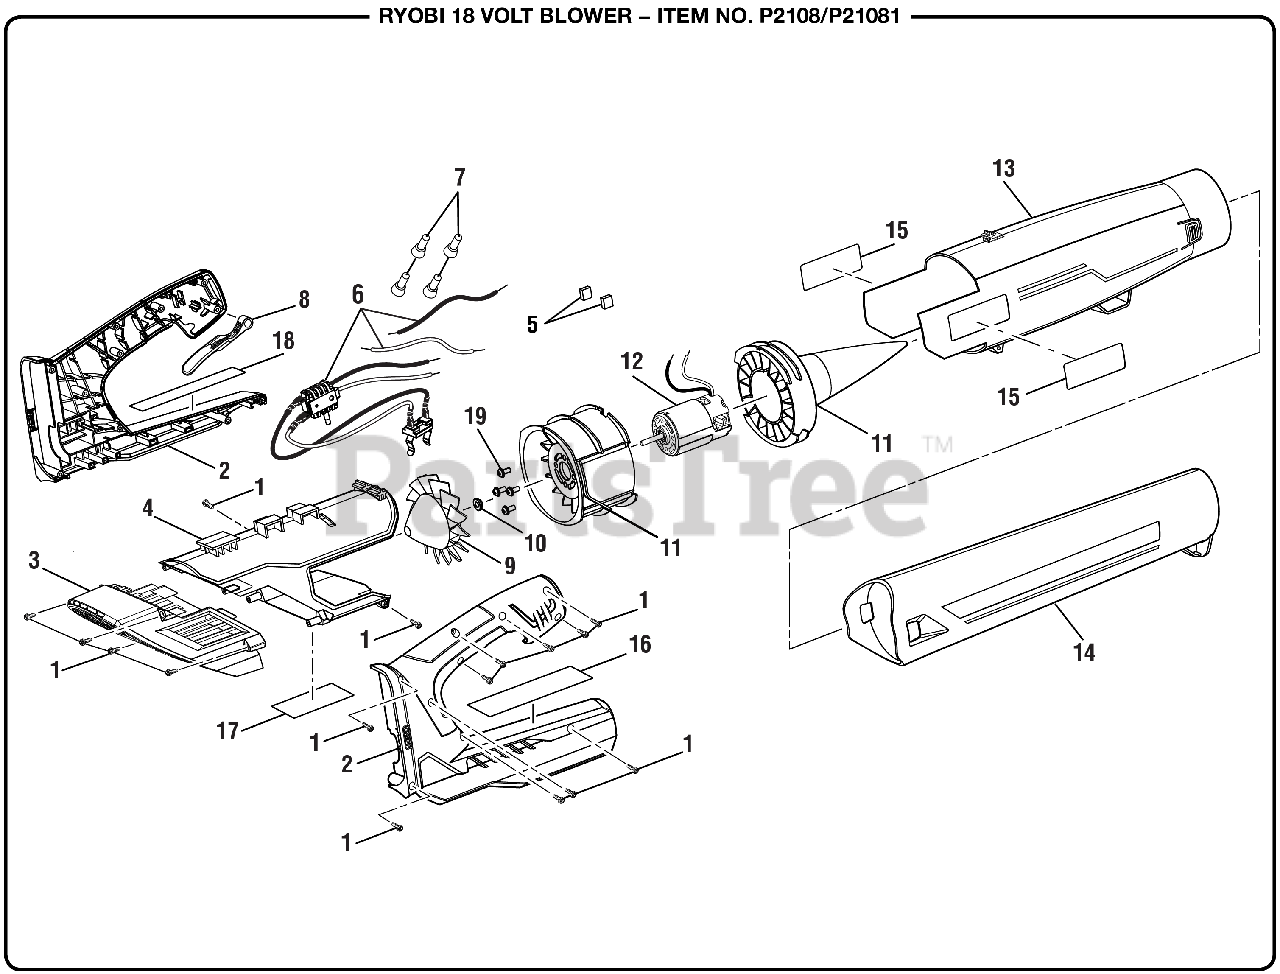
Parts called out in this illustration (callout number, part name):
1	Screw (M4 x 14 mm, T15 Torx Pan Hd.)
2	Handle Assembly
3	Inlet Guard
4	Inlet Housing Assembly
5	Rubber Block
6	Switch and Contact Plate Assembly
7	Wire Connector
8	Trigger Assembly (Variable Speed)
9	Fan Blade
11	Tail Cone Assembly
13	Blower Housing Outlet Assembly
14	Blower Tube
15	Logo Label (Ryobi)
16	Warning Label
17	Data Label
18	Warning Icon Label
19	Screw w/Lock Washer (M5 x 8 mm, Pan Hd.)
